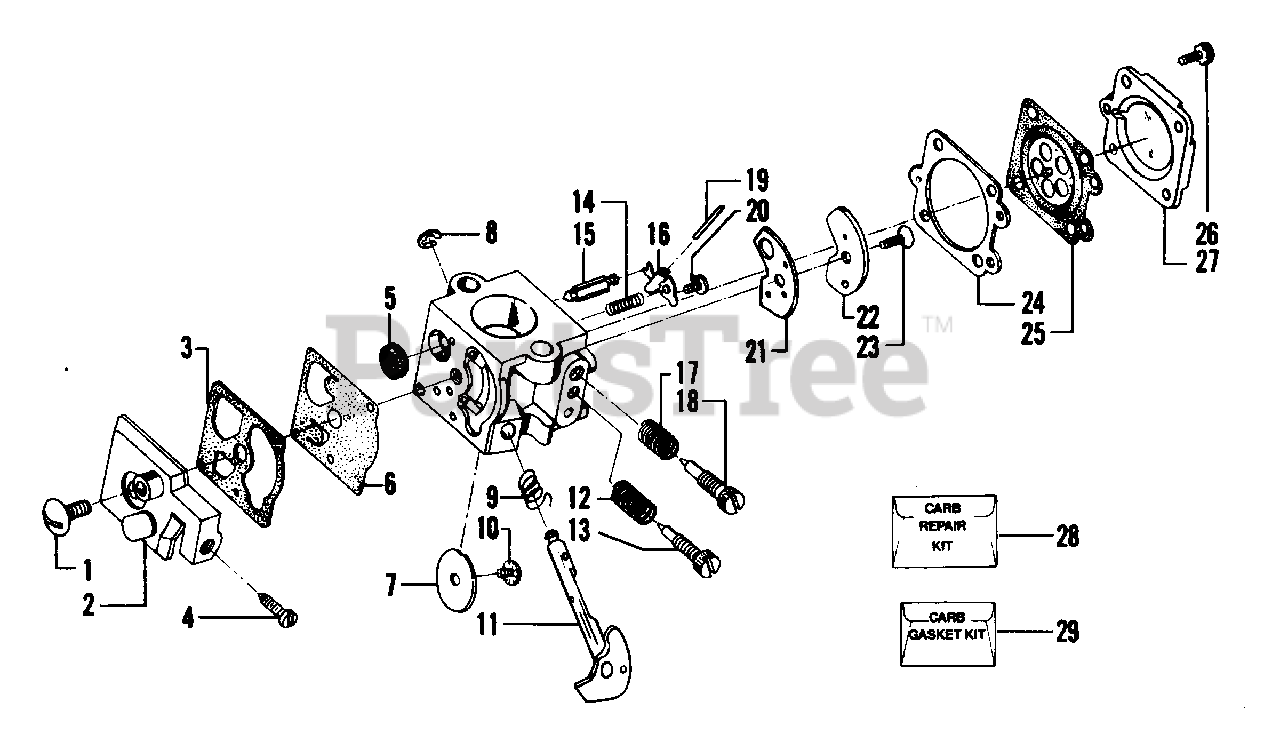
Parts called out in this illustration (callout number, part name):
1	Screw - Pump Cover
2	Pump Cover Ass'y (Inc.4)
3	Gasket - Pump
4	Screw - Idle Adjustment
5	Screen Inlet
6	Diaphragm - Pump
7	Valve - Throttle
8	Clip - Throttle Shaft
9	Spring - Throttle Return
10	Screw - Throttle Valve
11	Shaft Assembly - Throttle
12	Spring - Idle Needle
13	Needle - Idle
14	Spring - Metering Lever
15	Valve - Inlet Needle
16	Lever - Metering
17	Spring - Hi Speed Needle
18	Needle - Hi Speed
19	Pin - Metering Lever
20	Screw - Metering Lever Pin
21	Gasket - Circuit Plate
22	Plate - Circuit
23	Screw - Circuit Plate
24	Gasket - Metering Diaphragm
25	Diaphragm Assembly - Metering
26	Screw Assembly - Metering Cover & Throttle Shaft Clip
27	Cover - Metering Diaphragm
28	Kit Carb.-Kwik Repair (Inc. 3,5,6,10,14,15, 16,19,21,23,24,25)
29	Kit Carb.-Gasket/Diaphragm (Inc. 3,6,21,24, 25)
